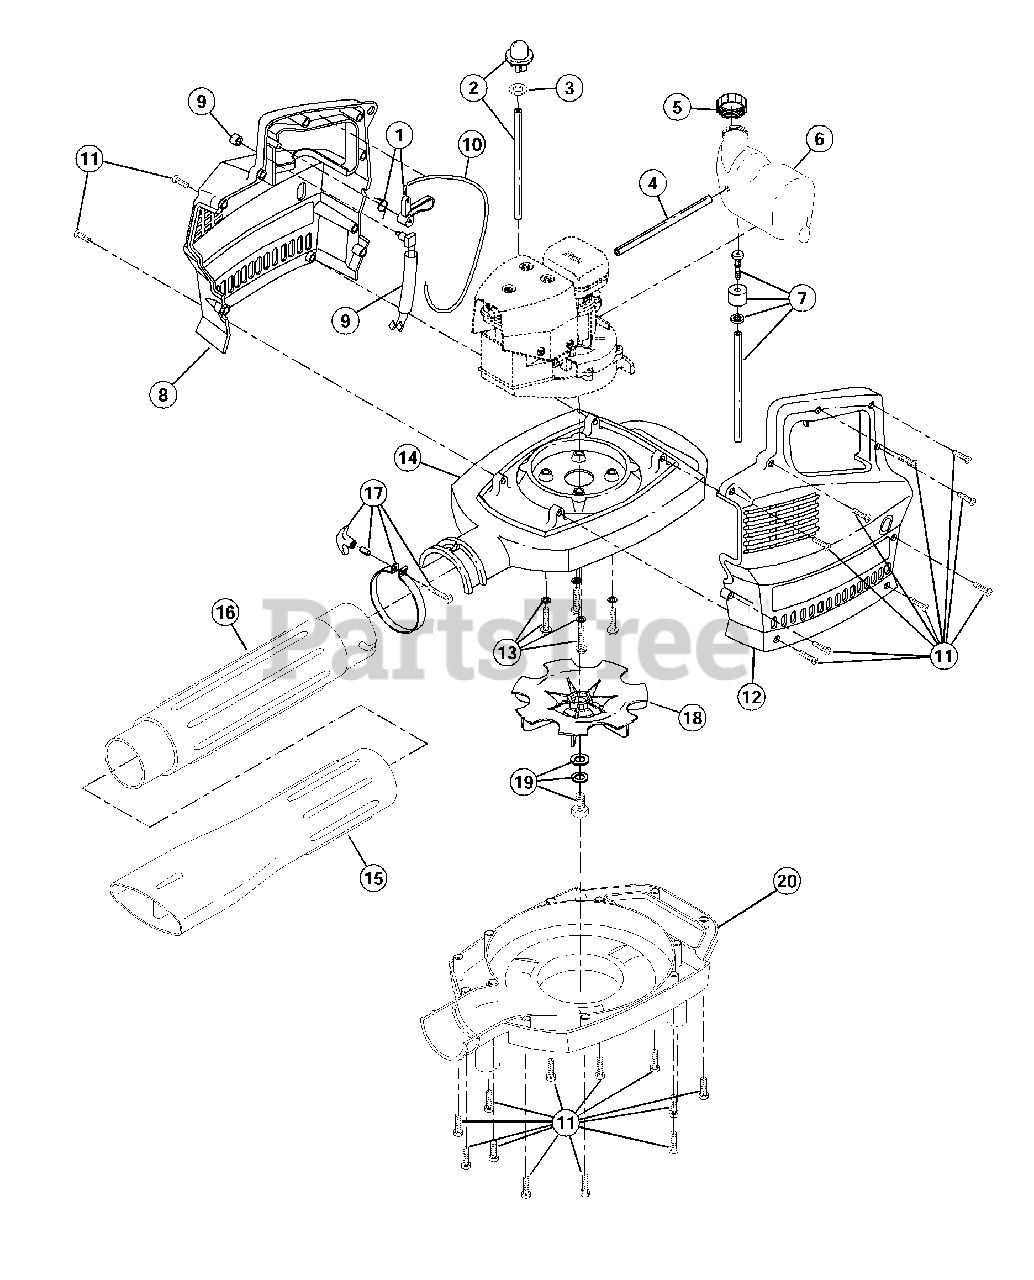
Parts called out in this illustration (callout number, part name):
1	Trigger Assembly
2	Primer Bulb and Hose Assembly
3	Primer Washer
4	Return Line
5	Fuel Cap Assembly
6	Complete Fuel Tank Assembly
7	Fuel Line Assembly
8	R.H. Engine Cover
9	Switch and Lead Assembly
10	Throttle Wire and Housing Assembly
11	Cover Screws
12	L.H. Engine Cover
13	Mounting Screws
14	Upper Blower Housing
15	Blower Tube W/Nozzle
16	Blower Tube
17	Clamp Assembly
18	Impeller
19	Mounting Bolt Assembly
20	Lower Blower Housing
